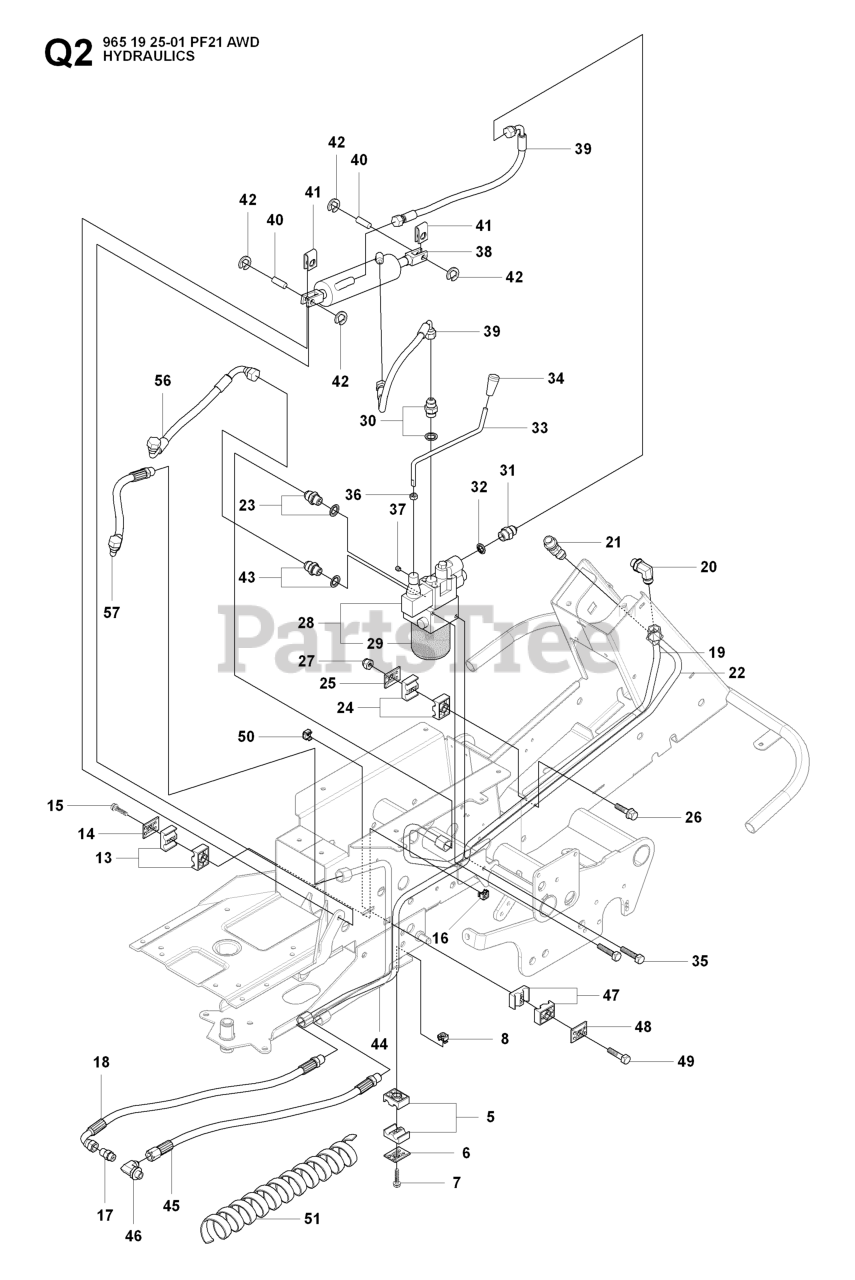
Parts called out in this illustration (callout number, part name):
5	PIPE CLAMP
6	COVER PLATE
7	SCREW EHHFM
13	PIPE CLAMP
24	PIPE CLAMP
27	LOCKNUT M6
29	FILTER
35	REPL BY 725 24 49-51
36	NUT
42	RETAINING RING SGA 10
47	PIPE CLAMP
